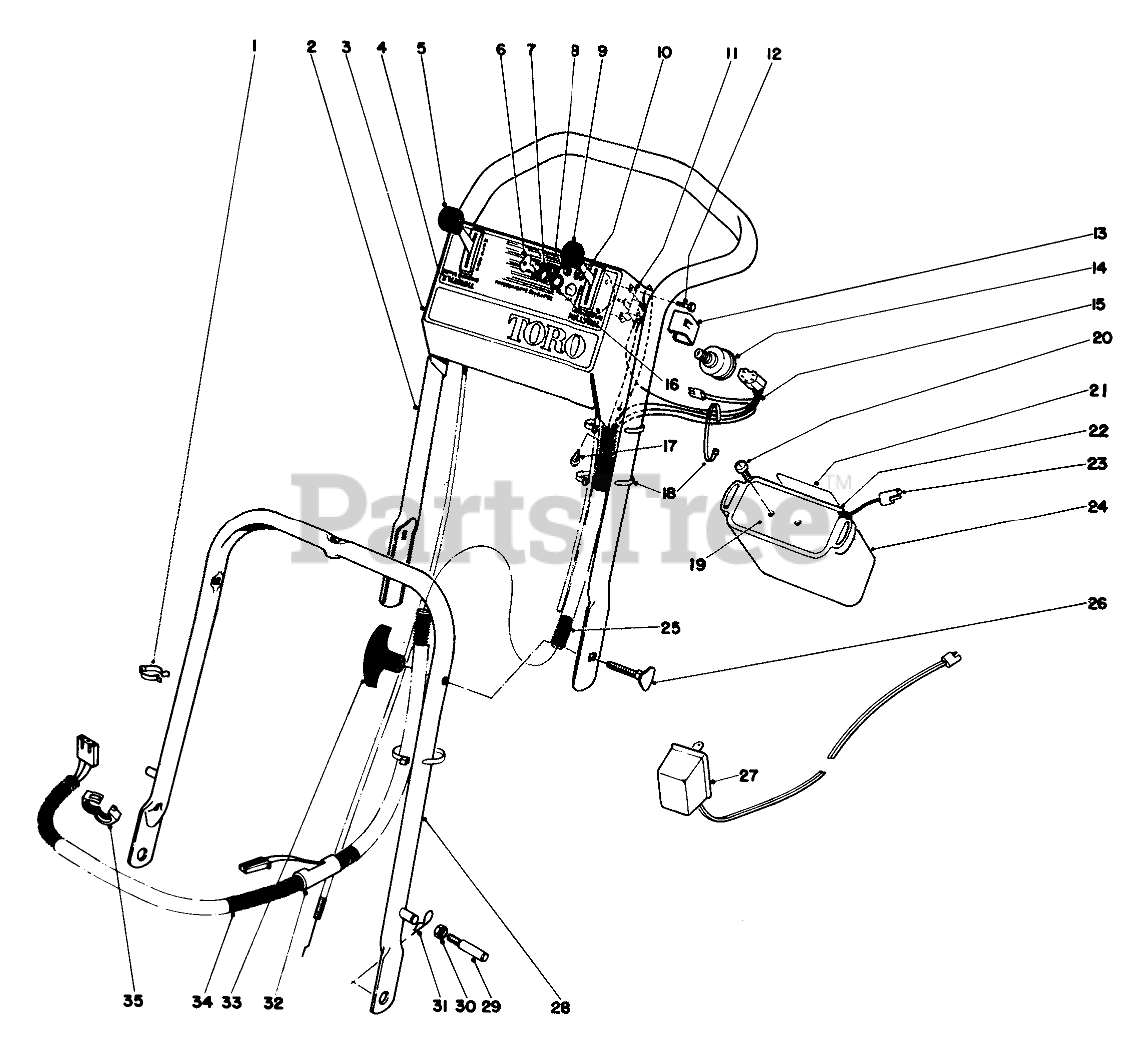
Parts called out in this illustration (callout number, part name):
2	UPPER HANDLE
3	Control Plate
4	Decal Control Plate
5	Control Throttle
6	Key
7	NUT-HH
8	NUT-HEX
9	Traction Control
10	WASHER-FLAT
11	CONTROL SWITCH
12	SCREW-HH
13	Cover Switch
14	SWITCH-STARTER
15	Wire Harness
16	WASHER-TOOTH, INTERNAL
17	SCREW-HWHTF
18	TIE-CABLE
19	BATTERY COVER
20	10-190X1/2 PAN HD SCR
21	Decal
22	Battery Assembly (Incl. Ref. #19-21 & 23-24)
23	Plug & Wire
24	Battery Case
25	Cover Wiring Harnes Upper
26	SCREW-HANDLE
27	Charger
28	LOWER HANDLE ASM
29	HANDLE PIN
30	Nut
31	PIN-COTTER, HAIR
32	Breakout Fitting
34	Cover Wiring Harness Lower
35	RING FITTING
